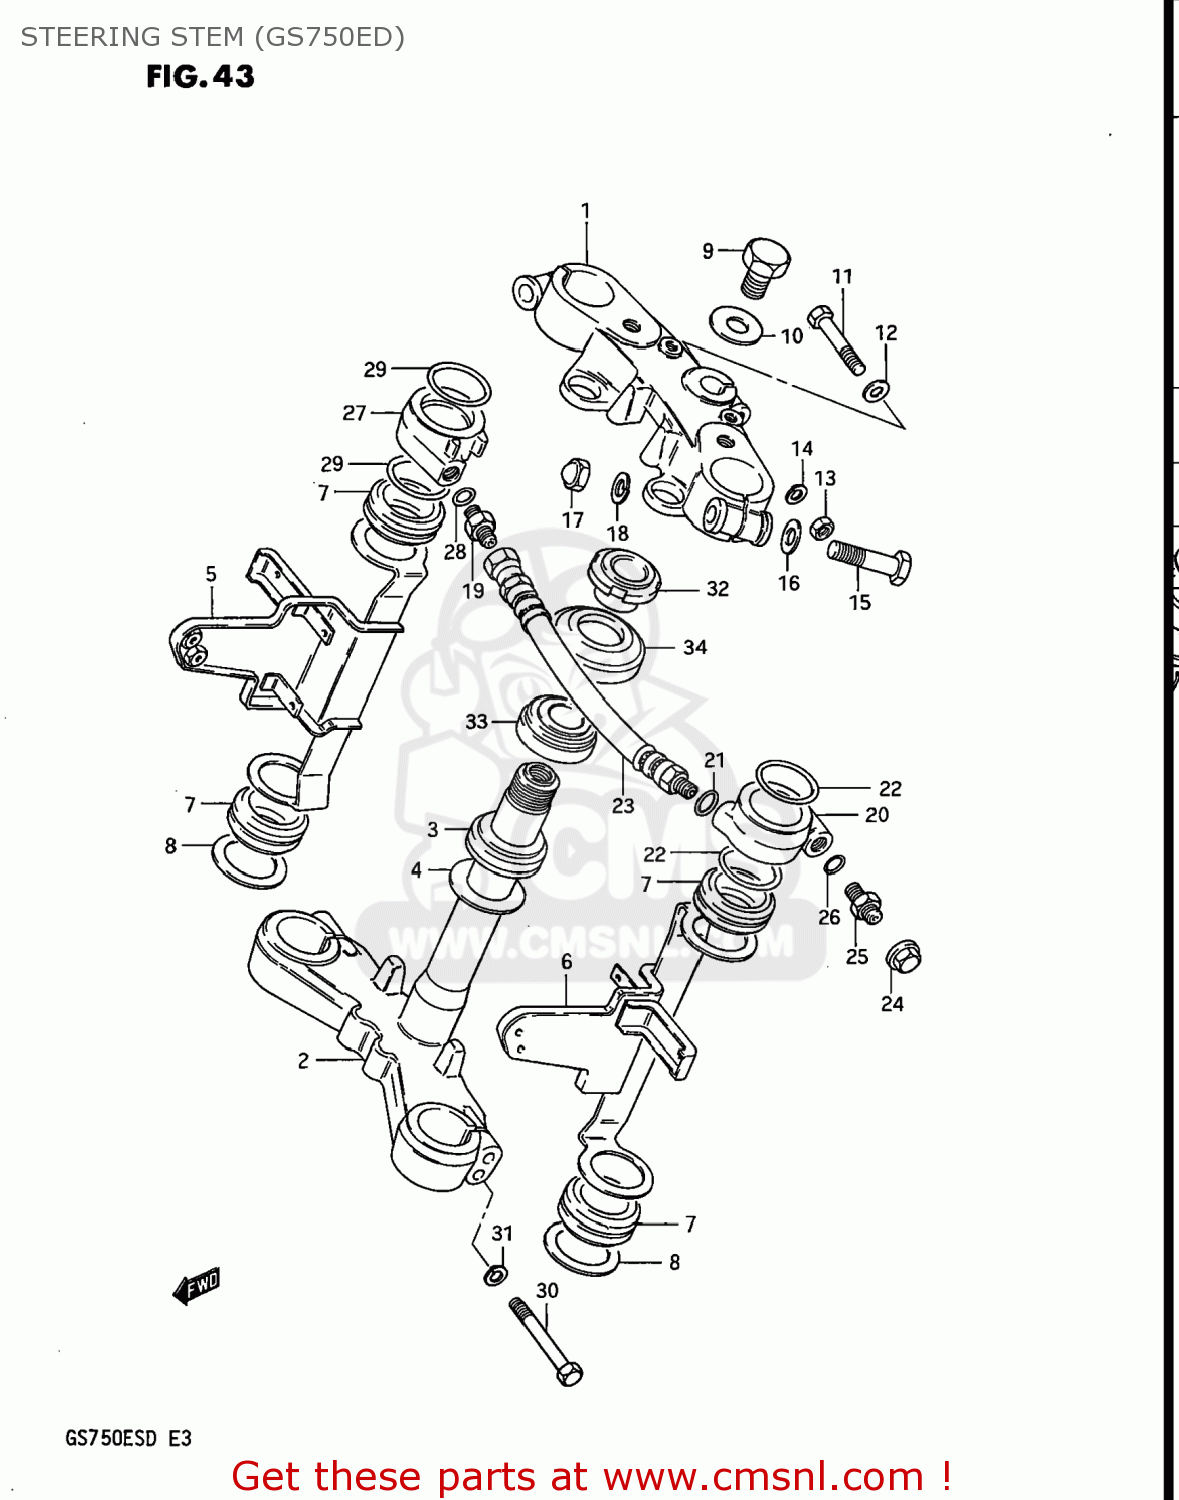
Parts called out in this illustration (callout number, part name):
1	HEAD,STEERING STEM
2	STEM,STEERING
3	BEARING
4	WASHER,THRUST
5	BRACKET,HEADLAMP HOUSING
6	BRACKET,HEADLAMP,LEFT
7	CUSHION,HEADLAMP BRACKET
8	WASHER
9	BOLT,STEERING STEM HEAD
10	WASHER
11	BOLT 8X50
12	WASHER
13	NUT 8MM
14	LOCK WASHER
15	BOLT 10X55
16	WASHER
17	NUT
18	LOCK WASHER
19	CONNECTOR
20	JOINT,AIR,LEFT
21	O-RING
22	O RING
23	TUBE,JOINT
24	CAP,FRONT FORK AIR VALVE
25	VALVE,AIR
26	O-RING
27	JOINT,AIR,RIGHT
28	O-RING
29	O RING
30	BOLT
31	LOCK WASHER
32	NUT,STEERING STEM
33	TAPER,ROLLER BEARING
34	DUST SEAL,STEERING UPR
